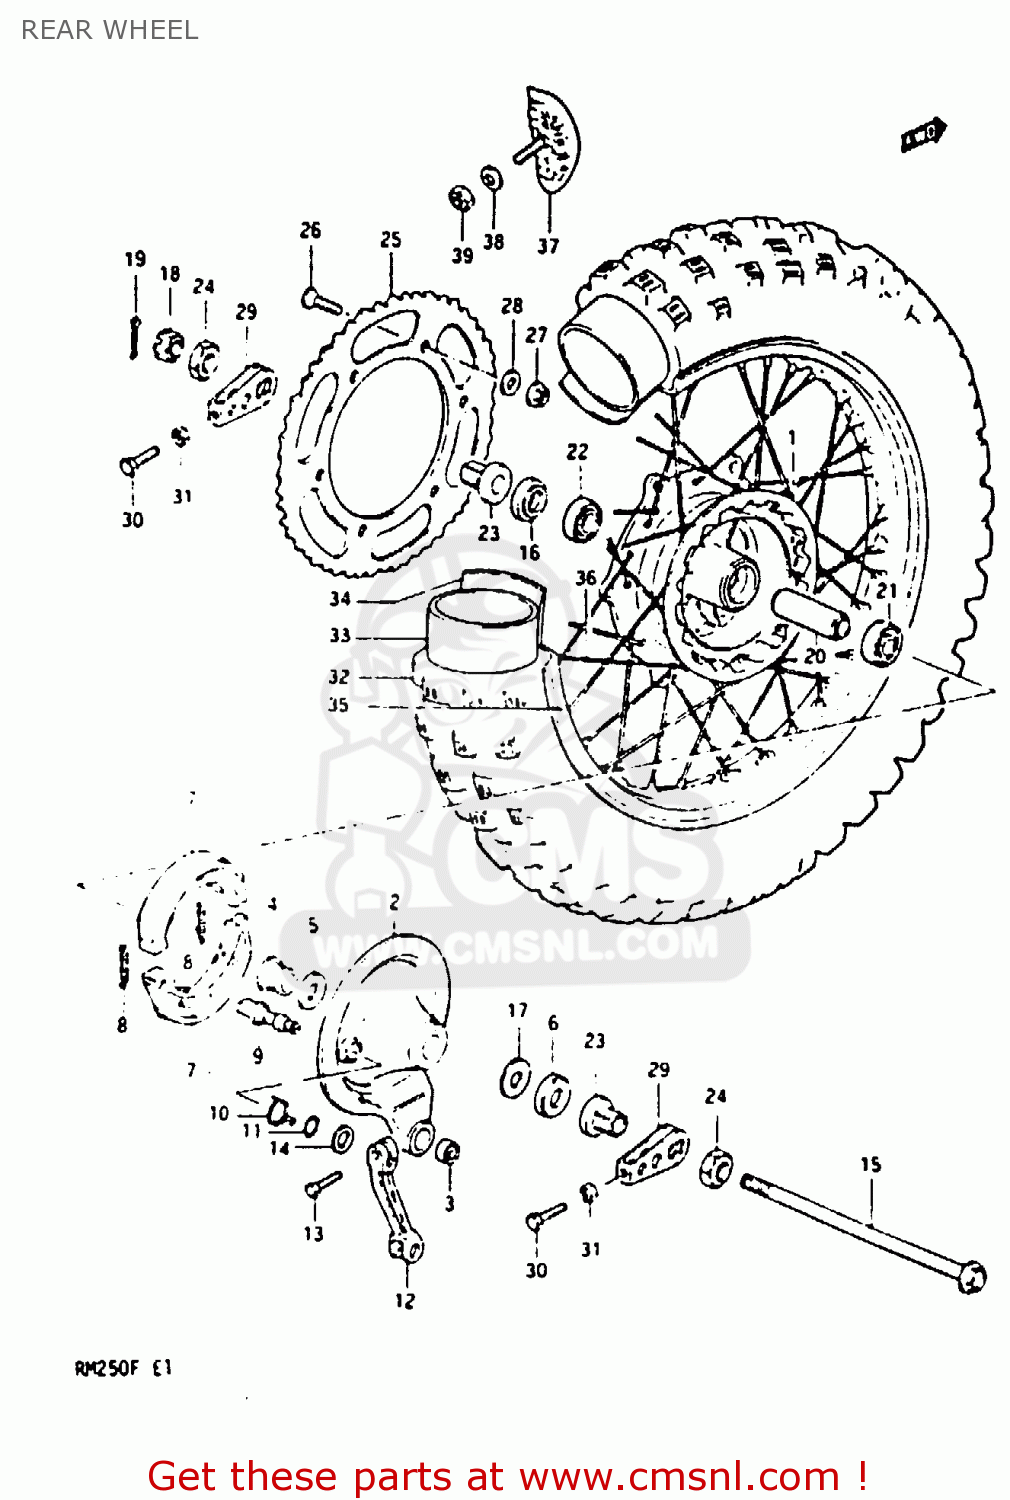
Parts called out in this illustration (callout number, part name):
1	DRUM,REAR HUB
2	PANEL SET
3	BEARING
4	SPACER,REAR HUB PANEL
5	SEAL,OIL(24X31X5)
6	CVR,RR BRAKE AHR PNL DUST SEAL
7	SHOE,BRAKE
8	SPRING,BRAKE SHOE
9	CAM,FR BRAKE
10	SPRING
11	O RING(D:2.5,ID:11.4)
12	LEVER,REAR BRAKE CAM
13	BOLT
14	WASHER(12.5X20X1)
15	AXLE,REAR
16	SPACER,REAR AXLE,LEFT
17	WASHER
18	NUT
19	PIN,COTTER
20	SPACER,REAR HUB BEARING
21	BEARING
22	BEARING
23	SPACER,CHAIN ADJUSTER
24	NUT
25	SPROCKET,REAR
26	SCREW(8X40)
27	NUT
28	WASHER
29	ADJUSTER,CHAIN
30	BOLT
31	NUT
32	TIRE
33	TUBE,INNER
34	PROTECTOR,WHEEL,INNER
35	RIM,REAR WHEEL (2.15X18)
36	SPOKE SET,REAR
37	STOPPER,BEAD
38	WASHER
39	NUT
